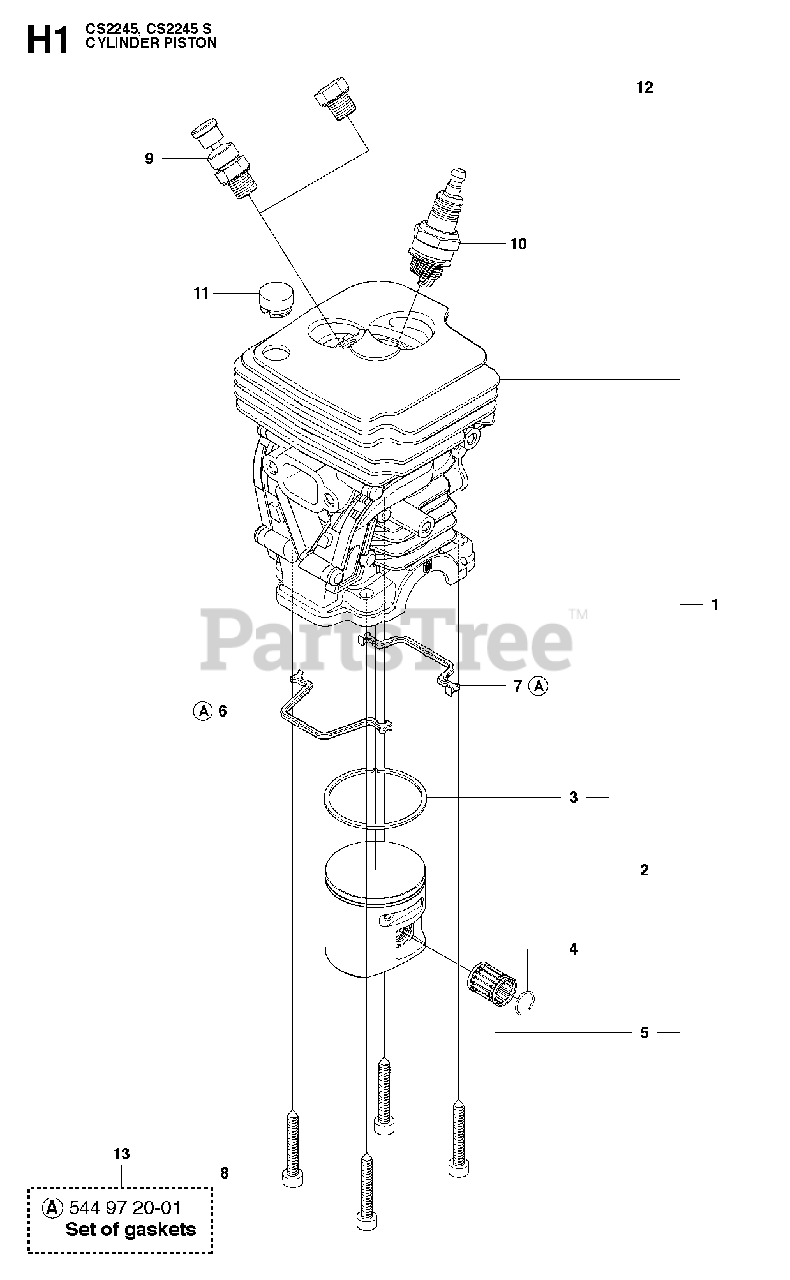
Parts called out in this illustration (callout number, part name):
2	PISTON ASSY
3	PISTON RING
4	CIRCLIP
5	NEEDLE BEARING
6	GASKET
7	GASKET
9	DECOMPRESSION VALVE
10	BPMR7A NGK SPARK PLUG
12	CYLINDER PLUG
13	GASKET KIT
